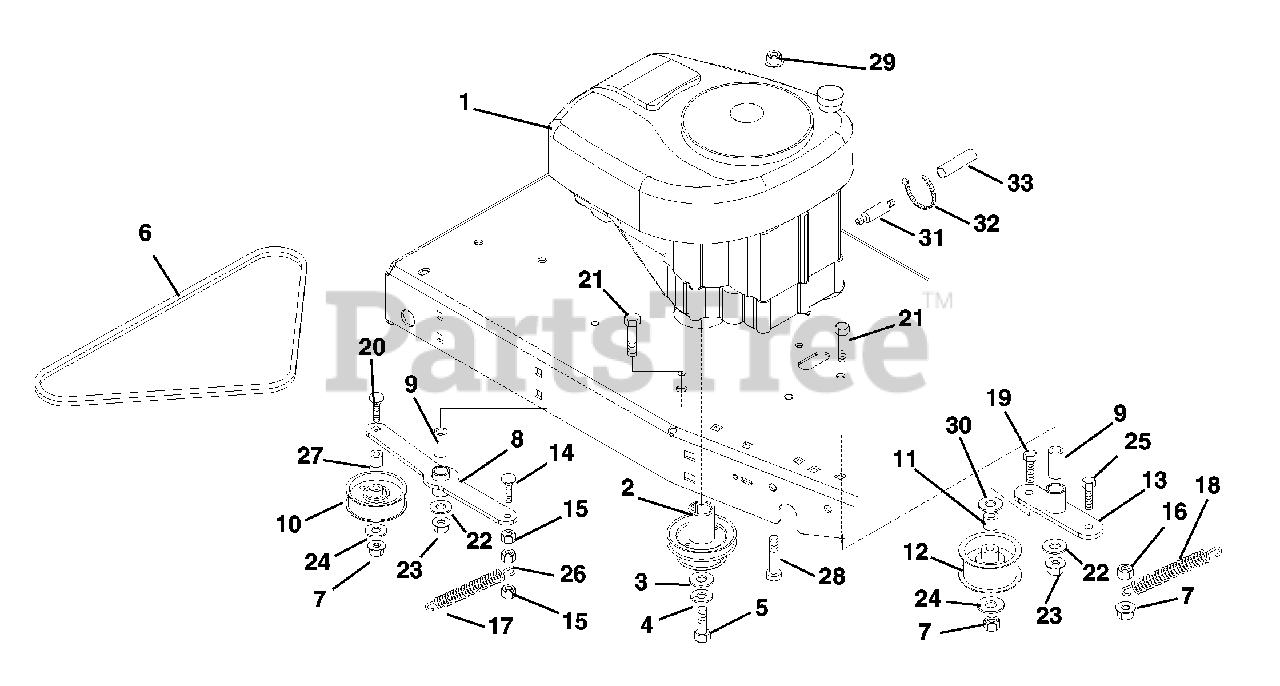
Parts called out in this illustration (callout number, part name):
1	Engine Group-12 HP (08200001) (030)
1	Engine Group-14 HP (08268600) (032)
2	Sheave, Engine (030)
2	Sheave, Engine (032)
3	Washer, Flat Steel .511 x 1.441 x .125
4	Washer, Locking .44 x .109 Regular
5	Bolt, Hex .44-20 x 1.50 Grade 5
6	V-Belt A-Section 14.50 x .516
7	Nut, Locking Top Flange .38-16
8	Weldment, Idler
9	Bushing, Sleeve .50 x .75 x 1.56
10	Idler-Pulley Flat 3.25 x .625
11	Bushing, Idler Spacer
12	Sheave 3.25 x 1.25
13	Bracket, Idler
14	Bolt, Round Head Square Neck .31-18 x 1.25 Grade 5
15	Nut, Locking Nylock Thin .50-13
16	Nut, Flange .375-16
17	Spring, Tension .075 x .75 x 2.25
18	Spring, Tension .08 x .687 x 5.16
19	Bolt, Hex .38-16 x 2.75 Grade 5
20	Bolt, Round Head Square Neck .38-16 x 2.00 Grade 5
21	Bolt, Hex .50-13 x 2.25 Grade 5
22	Washer, Flat Steel .563 x 1.38 x .109
23	Nut, Locking Top Flange .50-13
24	Washer, Flat Steel .438 x 1.00 x .083
25	Bolt, Hex .38-16 x 1.25 Grade 5
26	Nut, Spin Lock Flange .312-18
27	Bushing
28	Screw, Socket Head Button Head .31-18 x 1.50 Grade 8
29	Nut, Locking Top Flange .31-18
30	Washer, Flat Steel .43 x 1.00 x .160 (031)
31	Valve, Oil Drain
32	Cable Tie
33	Tube, Oil Drain
